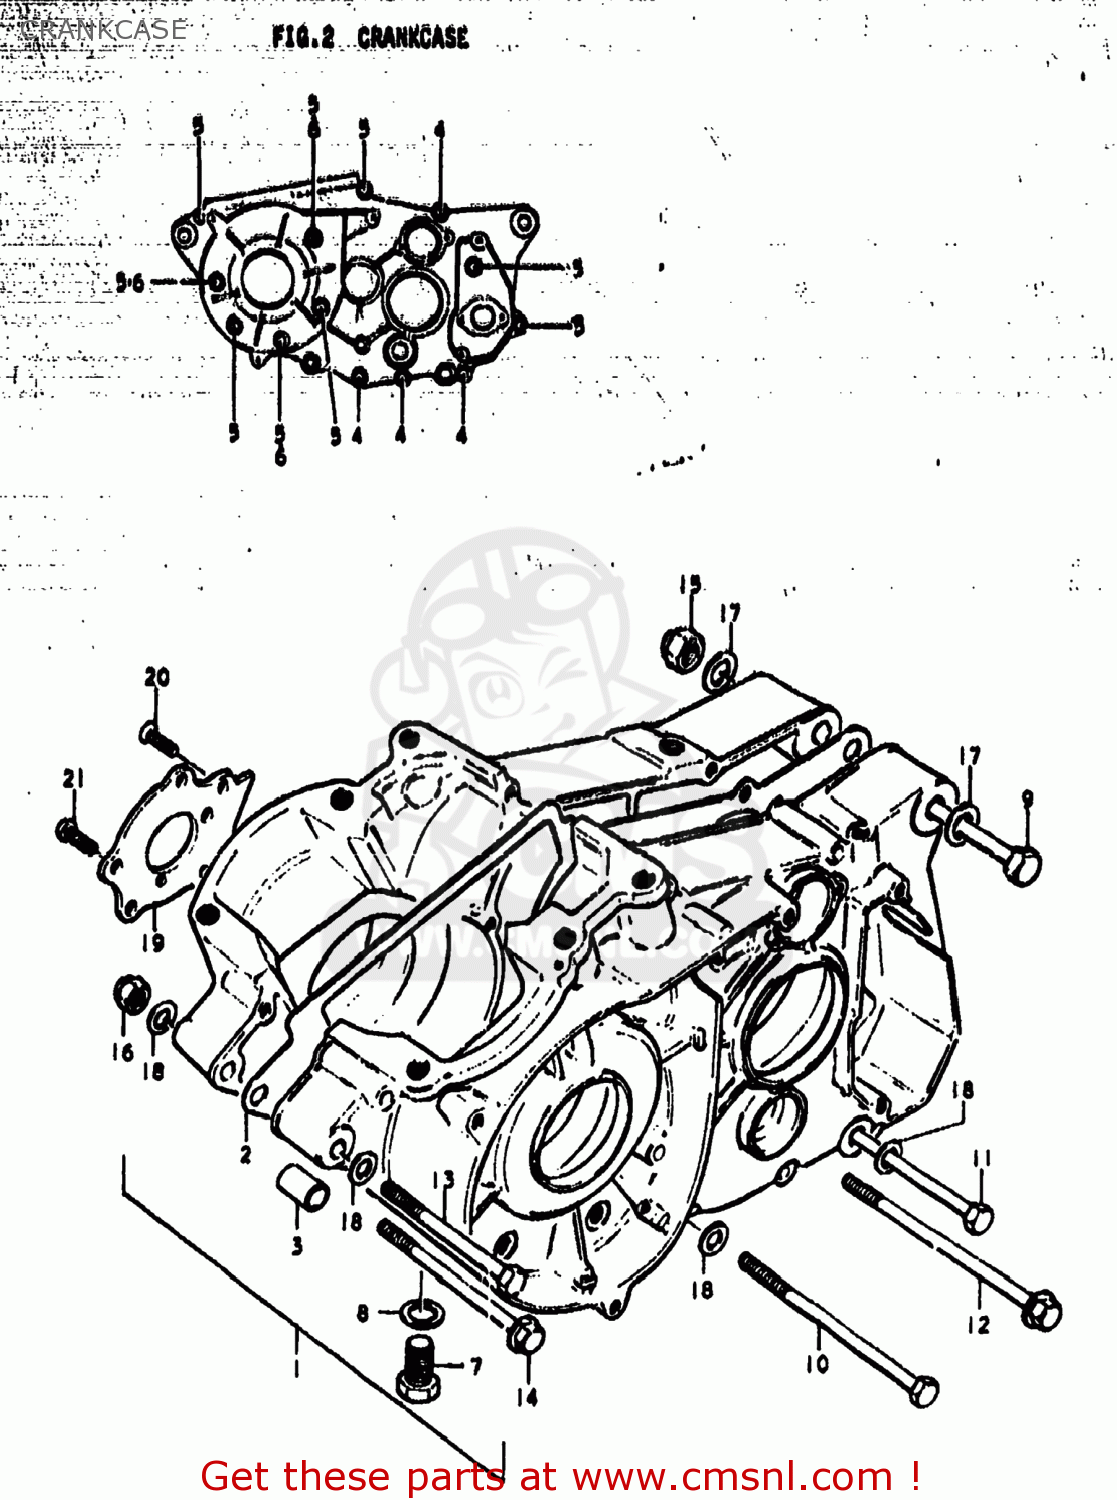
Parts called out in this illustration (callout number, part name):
1	CRANKCASE SET
2	GASKET,CRANKCASE (MCA)
3	PIN
4	SCREW 6X65
5	SCREW (6X45)
6	WASHER 6MM
7	PLUG
8	GASKET(14X19.2X2) (NAS)
9	BOLT
10	BOLT(8X145)
11	BOLT 8X120
12	BOLT
13	BOLT 8X100
14	BOLT
15	NUT
16	NUT
17	WASHER
18	WASHER
19	PLATE,OIL RESERVOIR
20	SCREW
21	SCREW
